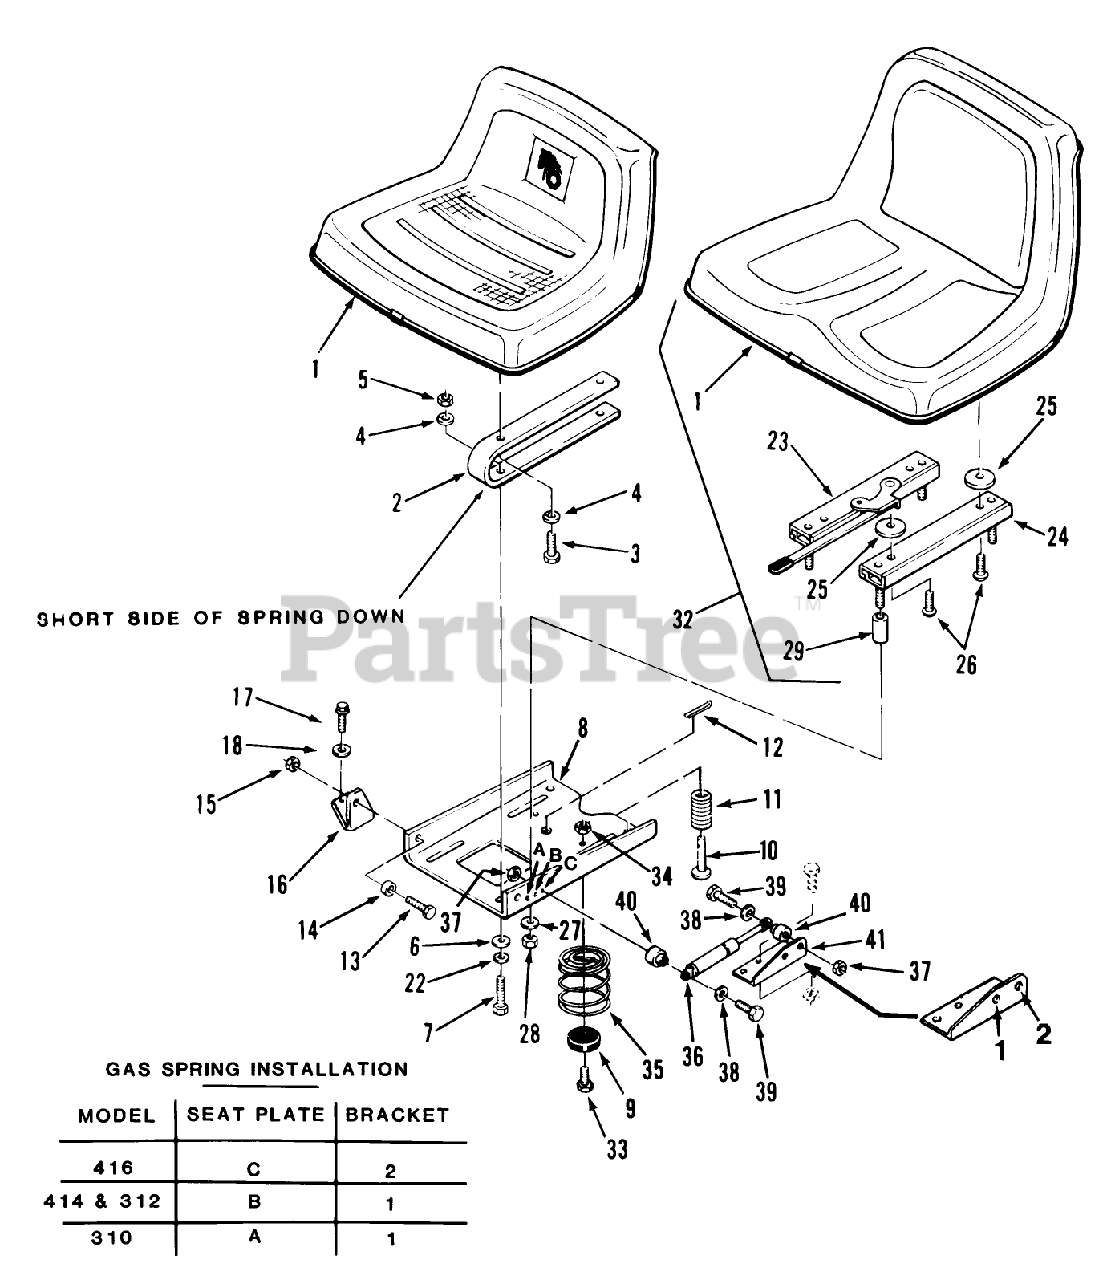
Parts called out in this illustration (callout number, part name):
6	WASHER 5/16 SAE
9	BUMPER
11	SPRING-SEAT SWITCH
14	BUSHING
16	BRACKET-PIVOT R.H *B (NS)
16	BRACKET-PIVOT L.H *B
18	WASHER 5/16 SAE
25	SPACER-NYLON
35	SPRING-SEAT NYLON
36	GAS SPRING
40	SPACER
41	BRACKET-CYLINDER *R
